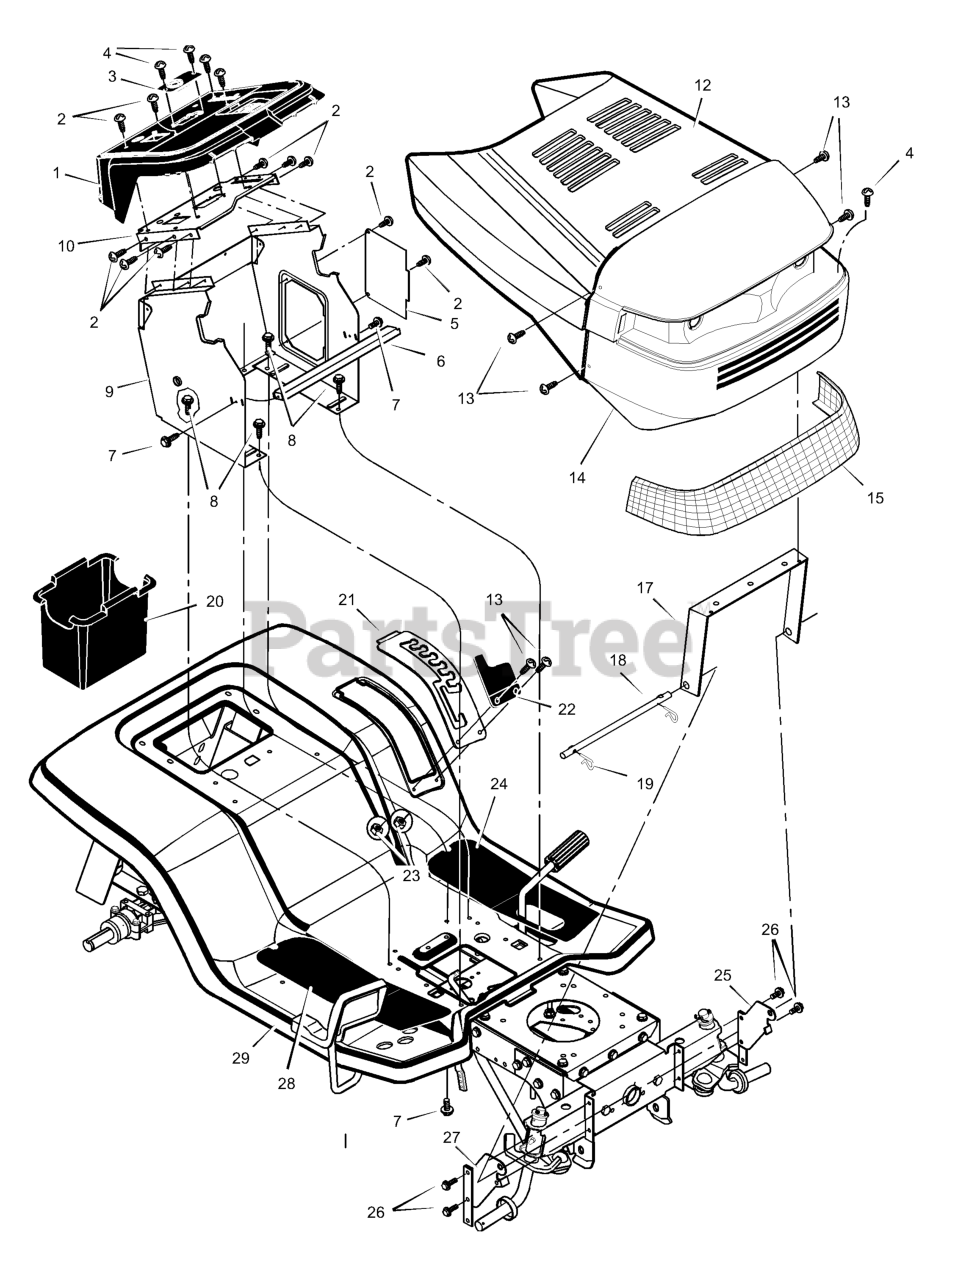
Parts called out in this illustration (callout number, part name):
2	Screw
3	Bearing, Upper Steering
5	Panel, Side Access
6	Channel, Support
9	Support, Dash
10	Plate, Dash
13	Bolt, Shoulder
14	Grille
17	Brace, Grille
18	Rod, Pivot
19	Pin, Hair
20	Container, Battery
21	Plate, Lift Detent
24	Mat, Left
25	Support, Left Grille
27	Support, Right Grille
28	Mat, Right
29	Deck, Seat
30	Decal, Left Hood
